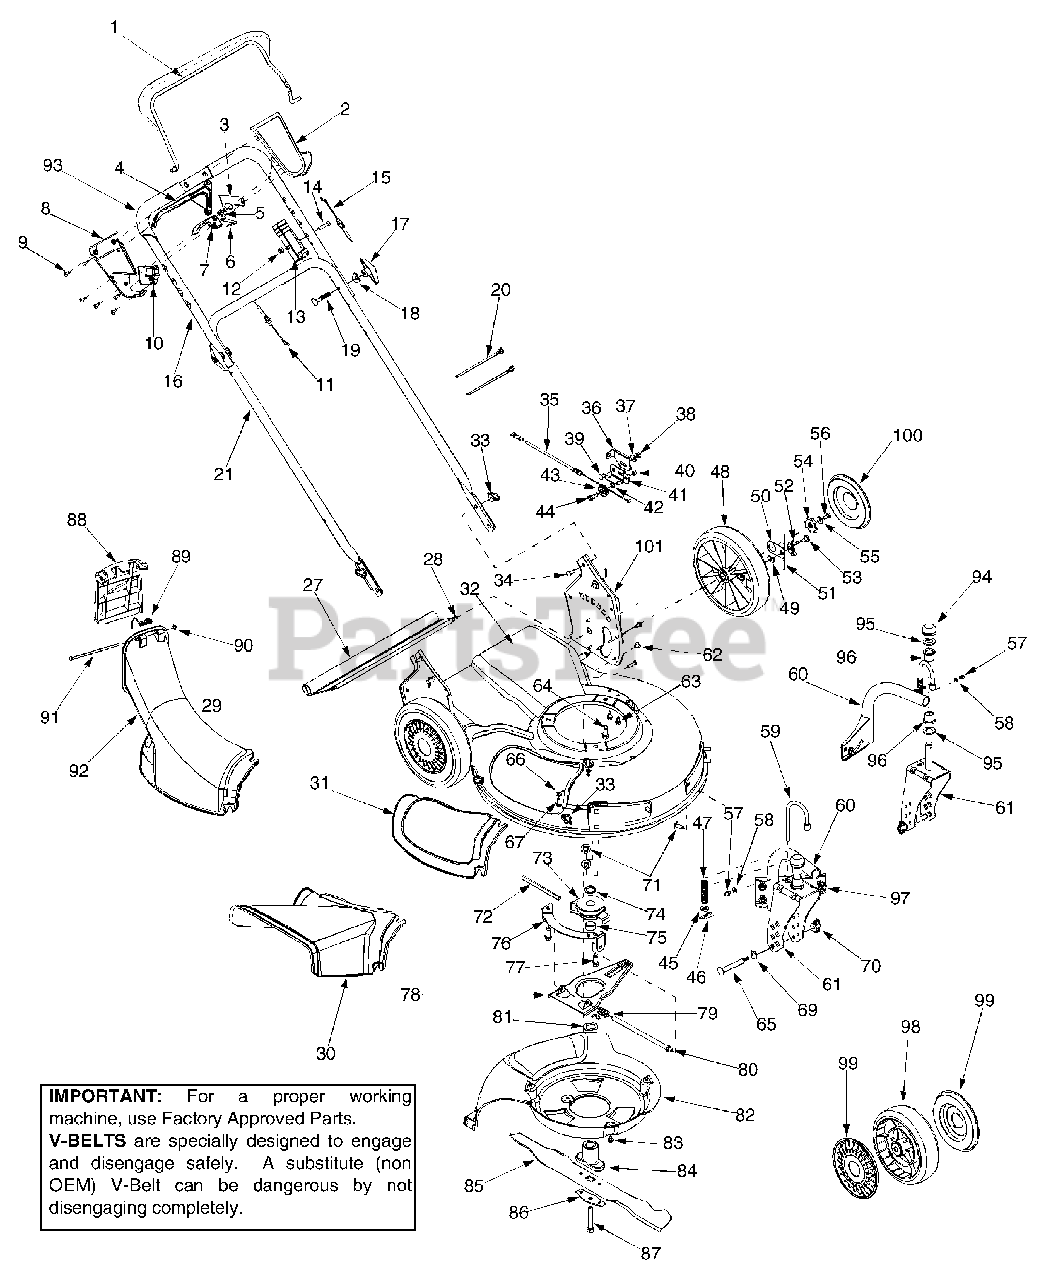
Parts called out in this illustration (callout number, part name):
1	Control Handle
2	Upper Control Handle
3	3-Speed Rack Cable Bracket
4	Control Lever
5	Gear Insert
6	Shift Lever Spring
7	3-Speed Shift Lever
8	Lower Control Housing
9	C Sunk Tap Screw #10 x .75 Lg
10	Cable Mounting Cap
11	Drive Cable 51.0
12	Top Lock Nut 1/4-20
13	Control Housing
14	Oval C-Sunk Screw
15	Control Cable 47"
18	Saddle Washer .320 ID x .830 OD
19	Carriage Bolt 5/16-18 x 2.0
20	Cable Tie
27	Trail Shield
28	Trail Shield Wire
29	Chute Assembly
30	Side-Discharge Chute
31	Mulch Cover
34	Carriage Bolt 1/4-20 x .75
35	3-Speed Cable
38	Hex Nut 1/4-20
39	Carriage Screw 1/4-20 x .50
40	Hex Nut 1/4-28
43	Cable Roller
44	Shoulder Screw .375 ID x 1/4-14
45	Flat Washer .330 ID x .630 OD
46	Cotter Pin
47	Compresion Spring
48	Wheel 9 x 2
49	Top Lock Tab Weld Nut 1/4-20
50	Ratchet Pawl Plate
51	Plastic Spring Ratchet
53	Shld Screw .340 ID x .285 OD
54	Wheel Rachet
55	Bell Washer .265 ID x .75 OD
56	Hex Cap Screw 1/4-20 x .620
57	Grease Fitting
58	Flat Washer .203 ID x .403 OD
59	Wheel Pin Lock
62	Screw 1/4-14 x .500
63	Screw 1/4-14 x .625
64	Hex Washer Screw 3/8-16 x 1.0
65	Caster Axle
66	Flat Washer .344 ID x .62 OD
67	Carriage Screw 1/4-20 x .75
69	Wave Washer .531 ID x .781 OD
70	Wing Nut
71	Carriage Bolt 5/16-18 x .62
72	Belt 3/8 x 39.24
73	Pulley Assembly
74	Sleeve Spacer .88 ID x 1.13 OD
75	Sleeve Spacer .88 ID x 1.00 OD
77	Screw 3/8-18 x 1.0
80	Pivot Shaft
81	Wave Washer 1.38 ID x .88 OD
82	Baffle
83	Screw 1/4-20 x 3.75
84	Blade Adapter Kit
85	21" Mulching Blade
86	Blade Bell Support
87	Hex Bolt 3/8-24 x 2.5
88	Chute Door
89	Torsion Spring
91	Pivot Rod
92	Discharge Chute
93	Grip
95	Flat Washer.640 ID x 1.12 OD
96	Flange Bearing
97	Flange Lock Nut 5/16-18
98	Wheel 7 x 2
99	Hubcap - Spoke w/ Hole
100	Hubcap - Radial Spoke
